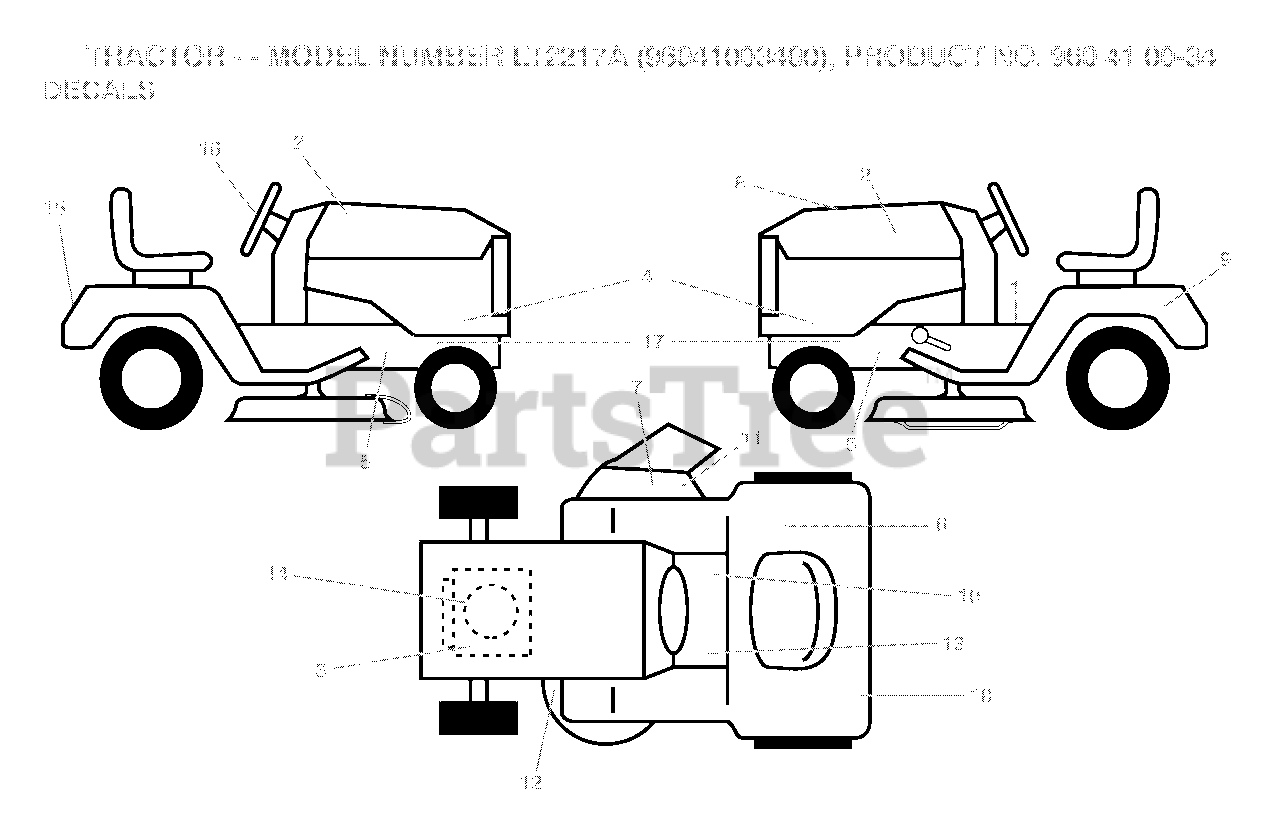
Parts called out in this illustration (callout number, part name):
7	DECAL.INTERNATIONL.CUTFINGER
9	DECAL BTRY SYMBOLS
10	DECAL PARK BRAKE
11	DECAL, DEFLECT WARNING
12	DECAL.V-BELT.SCHEMATIC.36/38/9
